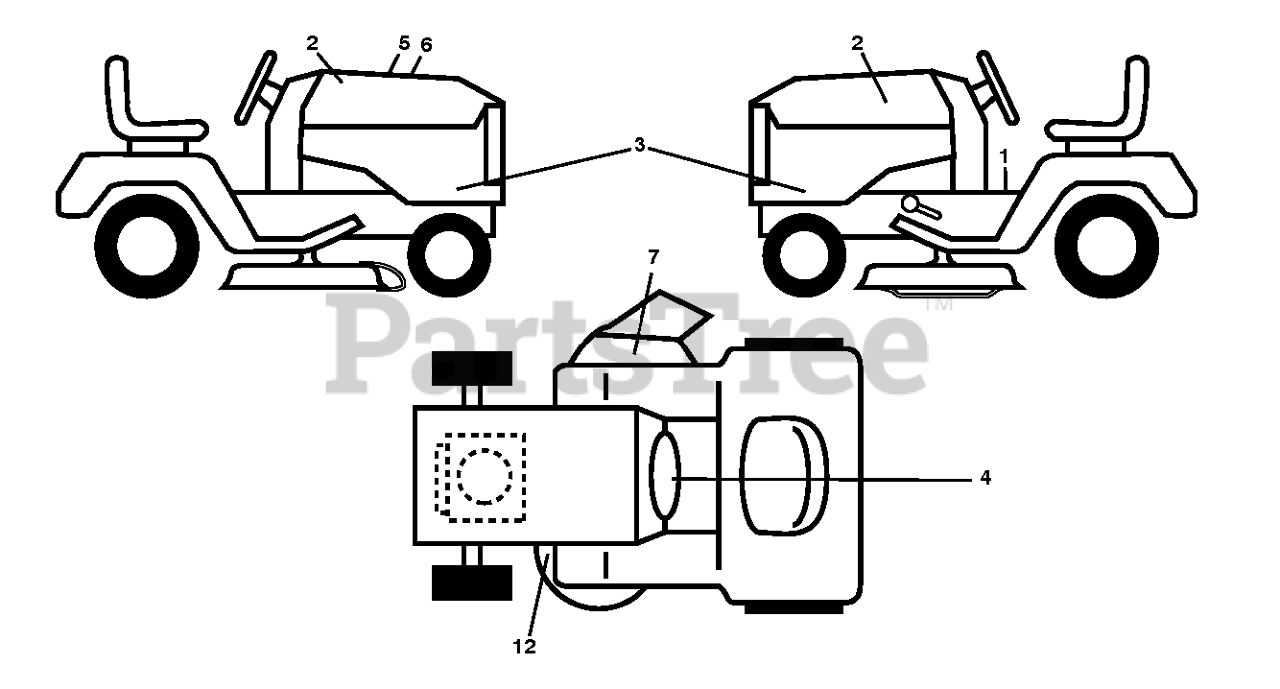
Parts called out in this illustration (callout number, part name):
1	DECAL.FENDER.WARNING.ENGLISH
2	DECAL.BADGE.170MM.TEXTLOGO.
3	DECAL.SIDE.PANEL.YTH18K46
4	DECALS.WARN.CA.SPKARREST/PROP
5	DECAL.WARNING.CUST.RESP.E85.
6	DECAL.RPL.KAW.FR.TLW.46E.K46L
7	DECAL, DECK DEFLECTOR, WARNING
12	DECAL.V-BELT.SCH.42/46"MEC/ELE
